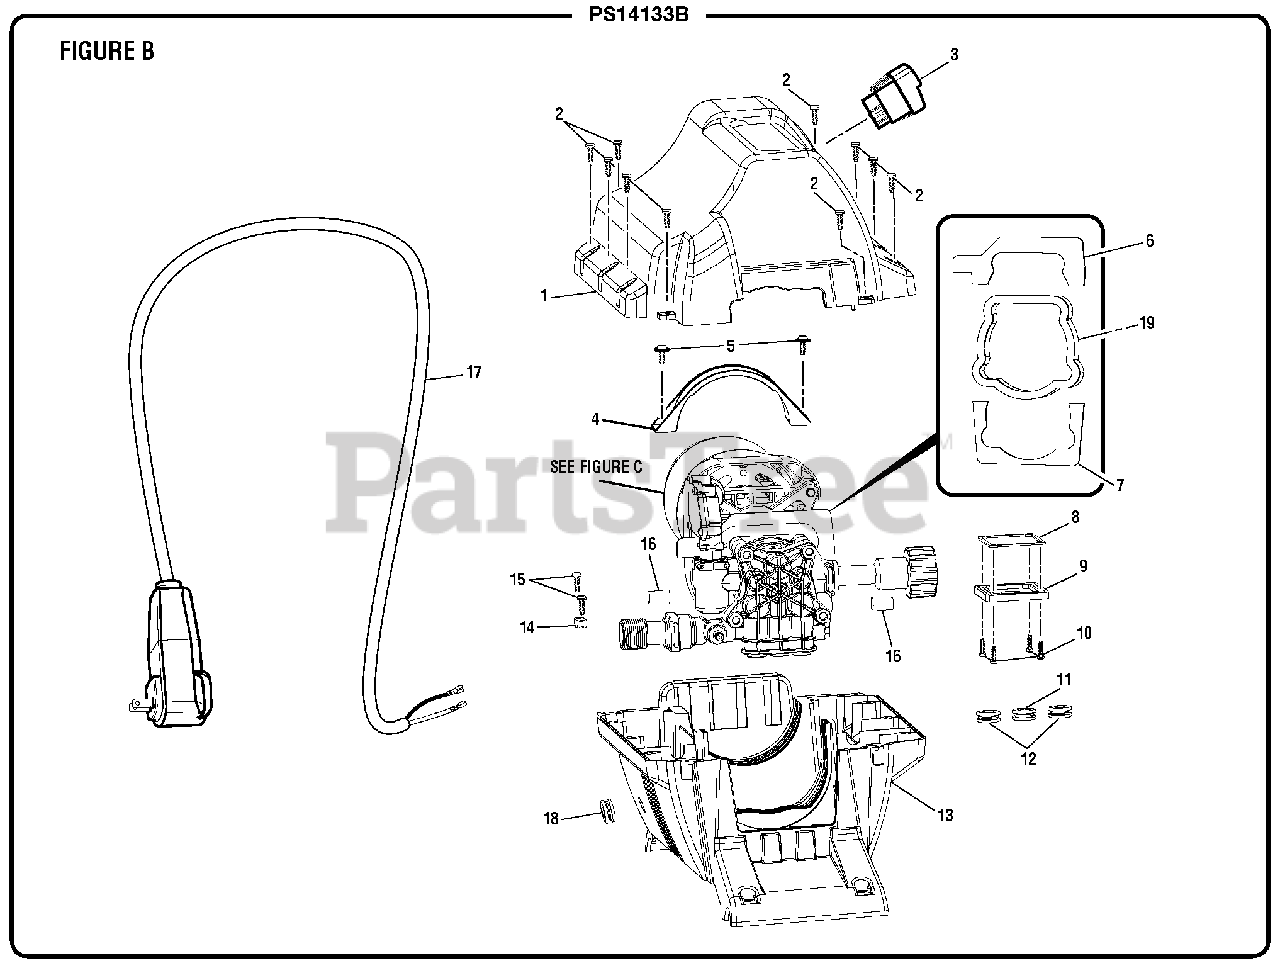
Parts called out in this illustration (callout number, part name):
1	Top Motor Housing
2	Screw (M4.2 x 15 mm, Pan. Hd.)
4	Motor Bracket
5	Screw w/ Washer (M4 x 16 mm, Round Hd.)
6	Upper Gasket
7	Lower Gasket
8	Switch Cover Gasket
9	Switch Cover
10	Screw (M2.9 x 14 mm, Pan Hd.)
13	Lower Motor Housing
14	Cord Clamp
15	Screw (M3.5 x 20 mm, Pan Hd.)
17	Power Cord
